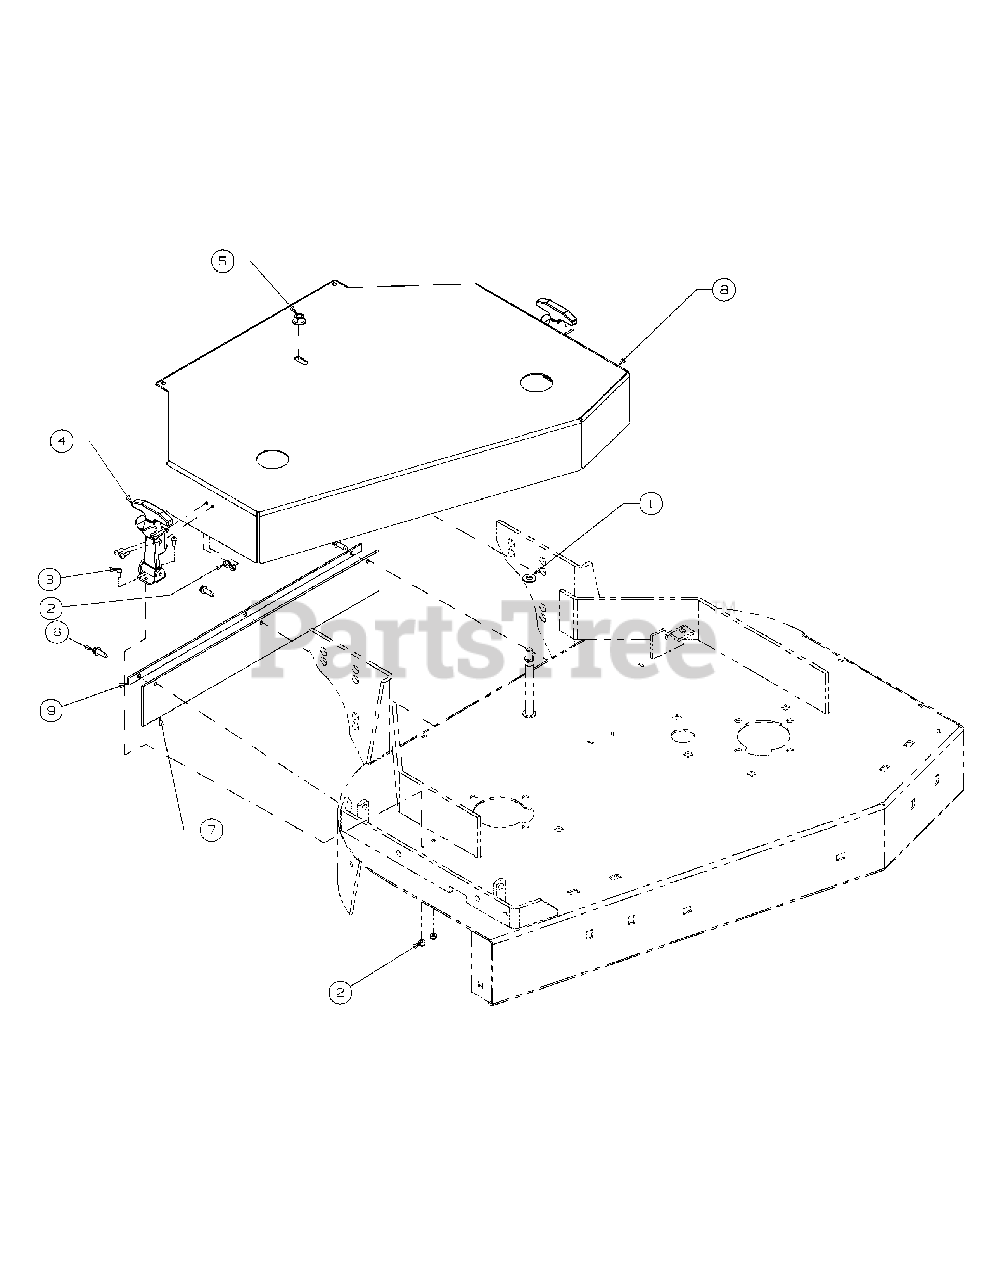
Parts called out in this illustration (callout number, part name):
1	Flat Washer, 3/8 Zinc
2	Lock Nut, Nylon Insert, 10-32
3	Phillips Head Screw, #10-32 x 1/2
4	Rubber Hood Latch
5	Hex Nut, 3/8-16, Flange Lock
6	Self Tapping Screw, 1/4-20 x 0.75
7	Trail Shield
8	Deck Cover, 36
9	Trailshield Plate
